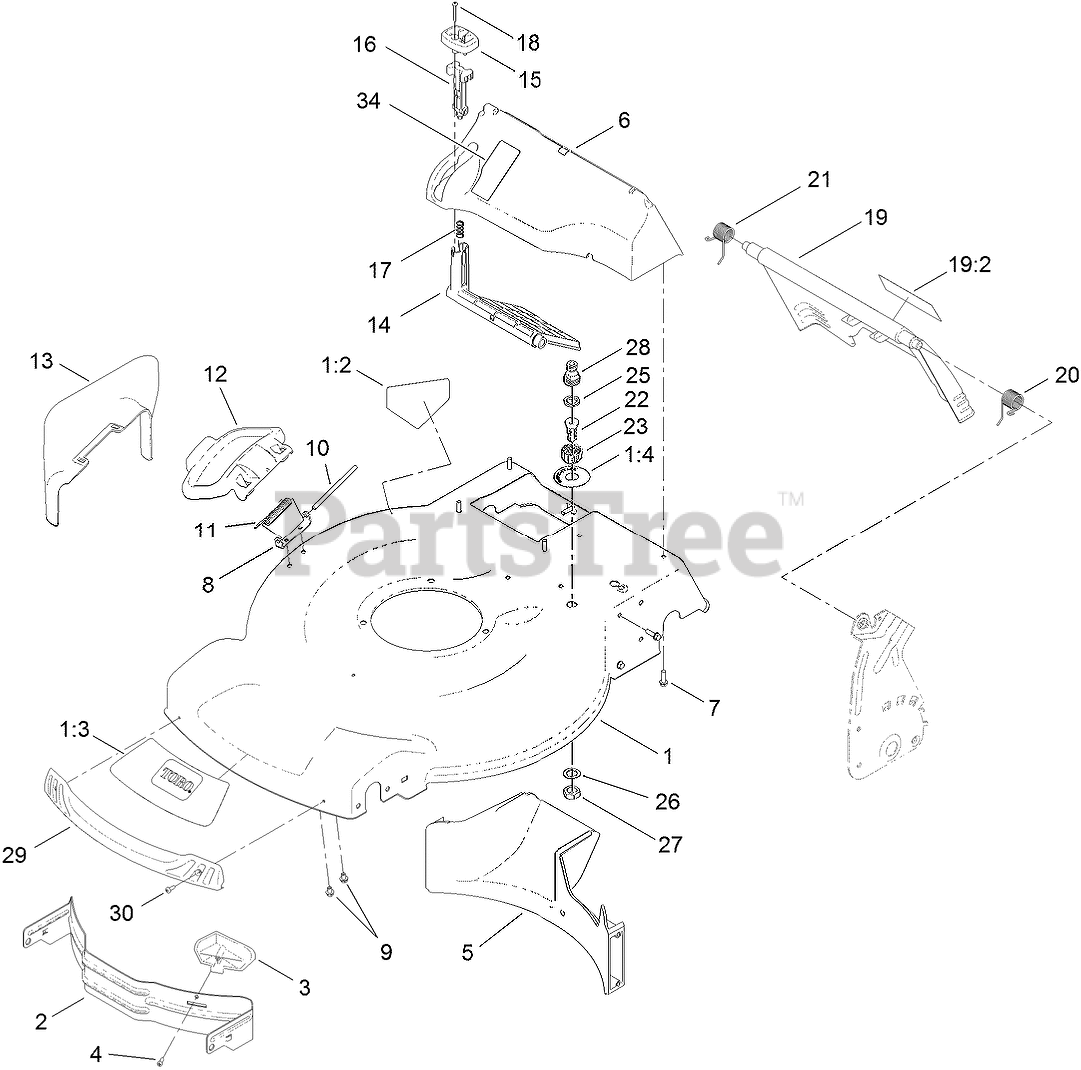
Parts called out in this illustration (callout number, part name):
1	HOUSING ASM
1:2	DECAL-DANGER
1:3	DECAL-RECYCLER
1:4	DECAL-PORT, WASHOUT
2	BAFFLE-FRONT
3	KICKER-FRONT
4	SCREW-PPH
5	BAFFLE-REAR
6	CHUTE-RECYCLE
7	SCREW-HWH
8	BRACKET-COVER
9	SCREW-HWH
10	ROD-COVER
11	SPRING-TORSION
12	DEFLECTOR-SIDE
13	CHUTE-DISCHARGE, SIDE
14	DEFLECTOR-RECYCLE
15	KNOB-RECYCLE
16	LATCH-RECYCLE
17	SPRING-COMPRESSION
18	SCREW-PPH
19	REAR DOOR ASM
19:2	DECAL-WARNING
20	SPRING-TORSION, LH
21	SPRING-TORSION, RH
22	PORT-WASHOUT
23	COUPLING-HOSE, WASHOUT PORT
25	WASHER-SEAL, WASHOUT PORT
26	WASHER-TOOTH, INTERNAL
27	NUT-JAM
28	ADAPTER-CONNECT, QUICK
29	BUMPER
30	SCREW-FORMING, THREAD
34	DECAL-BAG ON DEMAND
